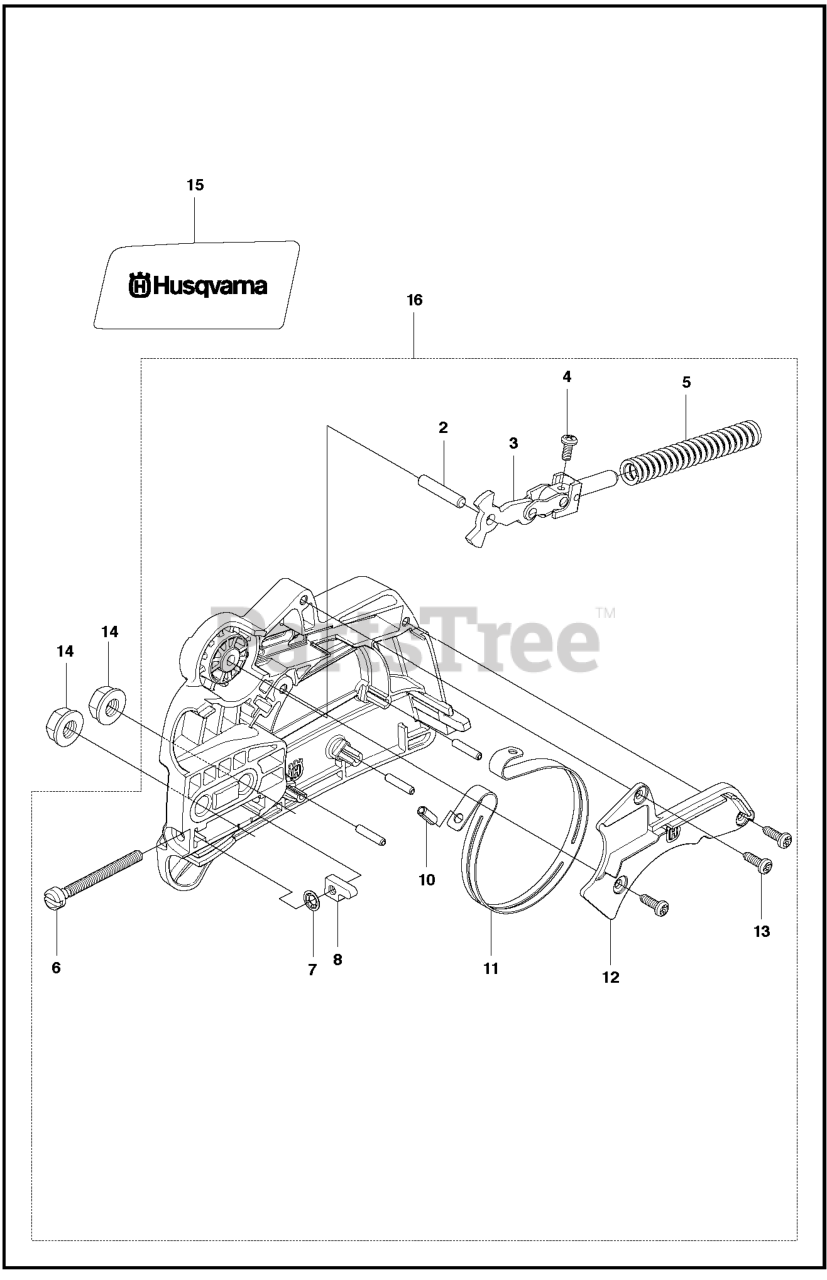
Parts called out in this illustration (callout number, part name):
2	PIN
4	SCREW M3.63-1.34 X 8MM
5	SPRING
6	BAR ADJUSTING SCREW
7	RETAINER
8	ADJUST PIN,BAR 36/41
10	PIN
11	BRAKE BAND
12	COVER CHAIN BRAKE GRAY HUSQ
13	SCREW 6-19X.437
14	BAR NUT
15	DECAL
16	CHAIN BRAKE ASSY ORANGE
